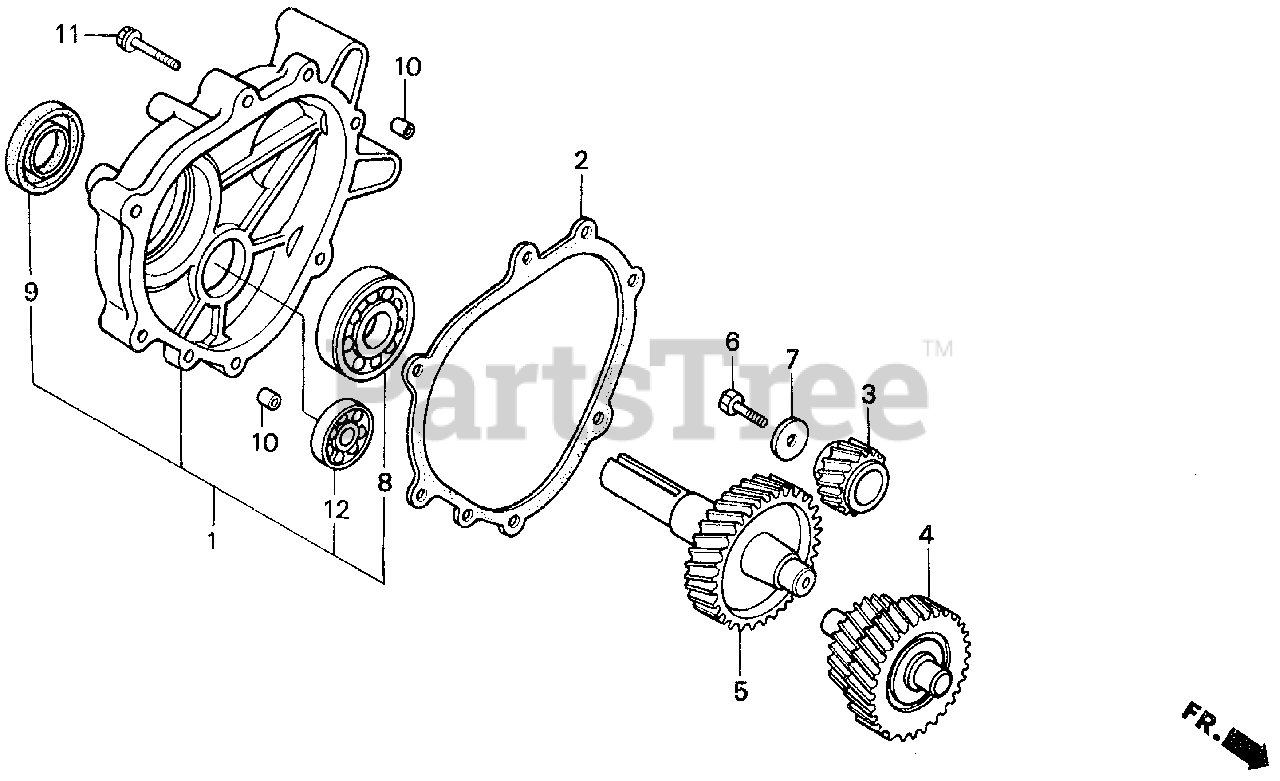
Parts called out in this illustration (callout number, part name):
1	COVER ASSY., GEAR CASE
2	GASKET, CHAIN CASE COVER
3	GEAR, PRIMARY DRIVE
4	COUNTERSHAFT
5	SHAFT, P.T.O. (L-TYPE)
6	BOLT, HEX. (8X25)
7	WASHER (8MM)
8	BEARING, RADIAL BALL (6202)
9	OIL SEAL (30X46X8)
10	PIN A, DOWEL (8X14)
11	BOLT, FLANGE (8X40)
12	BEARING, RADIAL BALL (6206)
